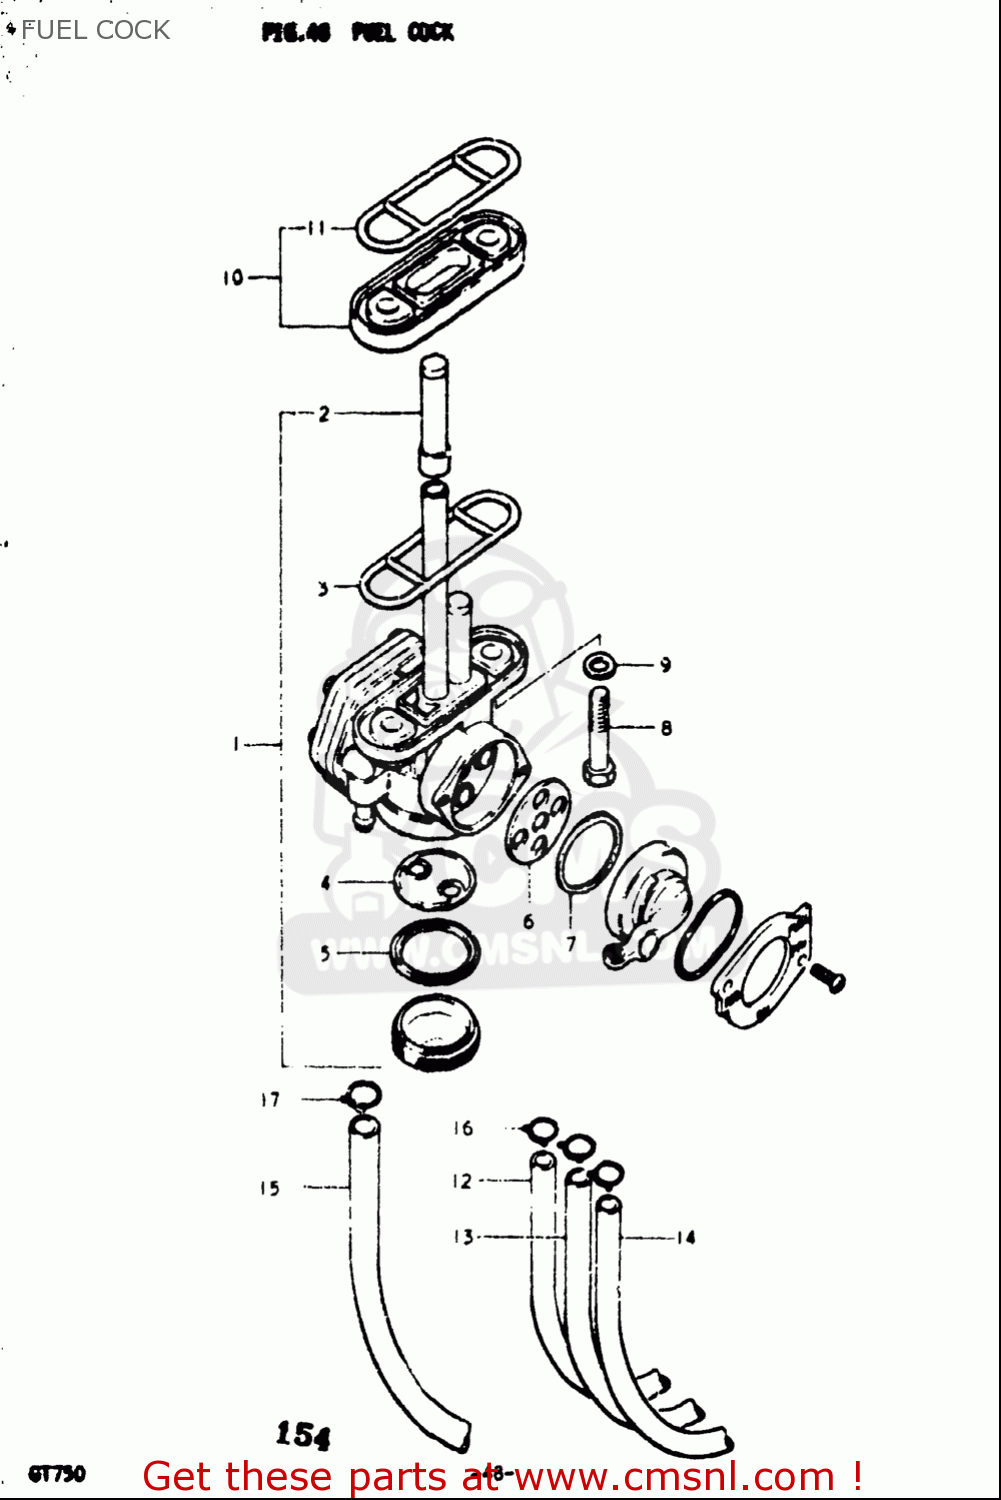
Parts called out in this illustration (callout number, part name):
1	COCK ASSY,FUEL
2	FILTER
3	GASKET, FUEL COCK (NAS)
4	FILTER,CUP
5	GASKET,CUP (NAS)
6	GASKET (NAS)
7	V SEAL,FUEL COCK
8	BOLT
9	GASKET(5.8X13X1.2) (NAS)
11	GASKET, FUEL COCK (NAS)
12	HOSE(5X8.2X2000)
13	HOSE(5X9X600)
14	HOSE(5X9X600)
15	HOSE(7X10.2X2000)
17	CLIP
